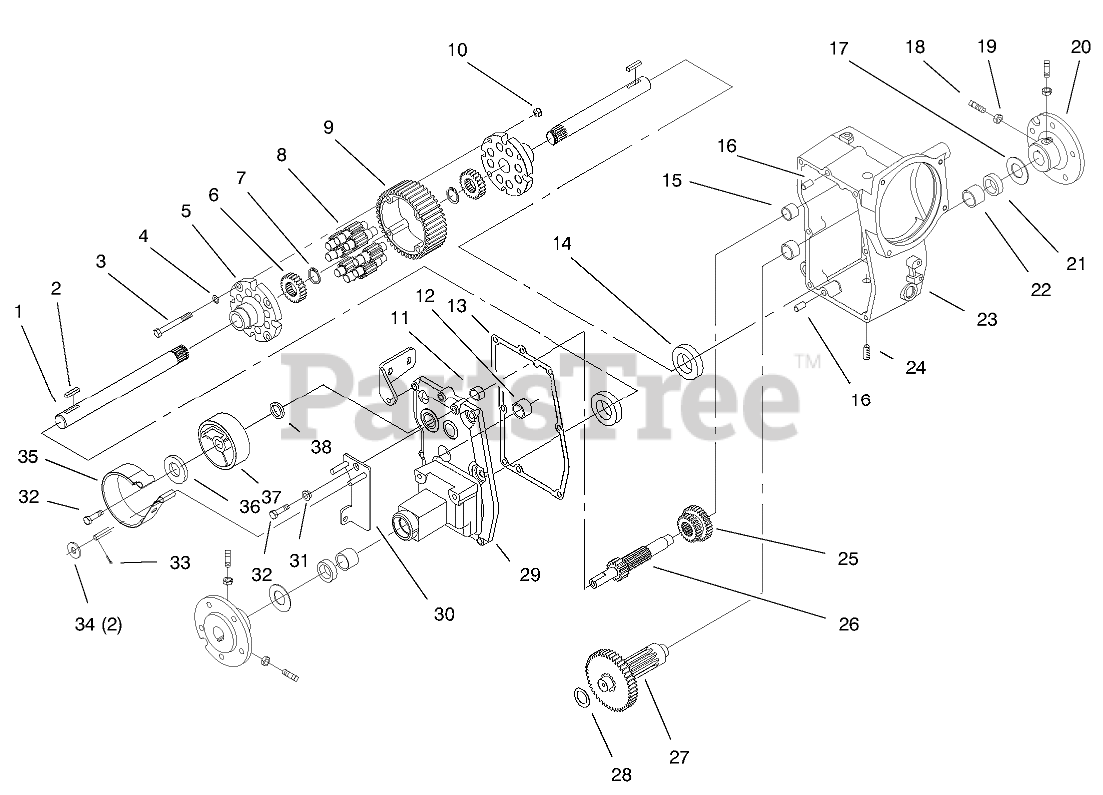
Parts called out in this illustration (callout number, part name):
1	AXLE-REAR
3	BOLT-HEX
4	WASHER
5	END CAP-DIFFERENTIAL
6	GEAR-AXLE DIFFERENTIAL
7	RING-SNAP
8	GEAR-PINION, 11T
9	GEAR-DIFFERENTIAL RING, 43T
11	BEARING-NEEDLE
12	BEARING-NEEDLE
13	GASKET-CASE
14	BEARING-BALL
15	BEARING-NEEDLE
16	PIN-LOCATING
17	WASHER-THRUST
18	SCREW-SET, SQH
19	NUT-JAM
20	HUB-WHEEL
21	SEAL-OIL
22	BEARING
23	CASE-LH
24	PLUG-PIPE
25	GEAR-SLIDING
26	SHAFT-BRAKE
27	GEAR ASM
28	WASHER-THRUST
29	CASE-RH
30	Arm-PIVOT, Brake
31	CAM-SPACER
32	SCREW-HH, LOCK
33	PIN-COTTER
34	WASHER-FLAT
35	BAND-BRAKE
36	WASHER
37	DRUM-BRAKE
38	SEAL-OIL
